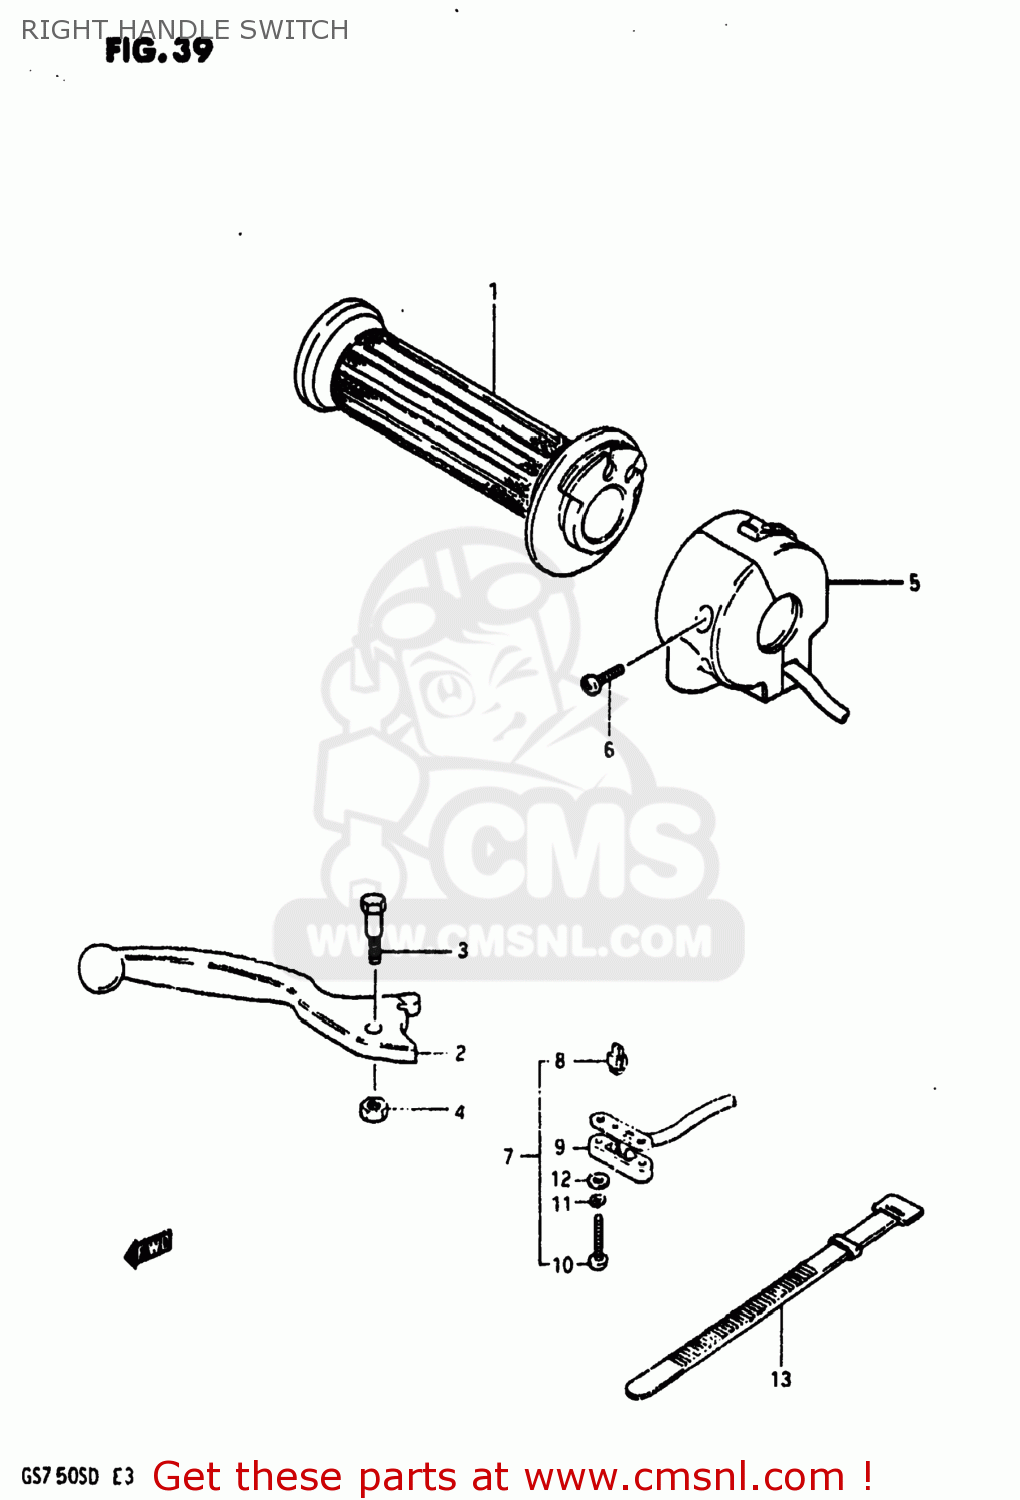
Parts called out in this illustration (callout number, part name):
1	GRIP,THROTTLE
2	LEVER,BRAKE
3	BOLT
4	NUT 6MM
5	SWITCH ASSEMBLY,HANDLE,RIGHT
6	SCREW
7	SWITCH ASSEMBLY
8	CONTACT,SWITCH
9	COVER,FR BK TERMINAL BASE
10	SCREW
11	LOCK WASHER
12	WASHER
13	CLAMP(L:120)
14	BUTTON,STARTER
15	SPRING,STARTER BUTTON
16	CONTACT,STARTER BUTTON
